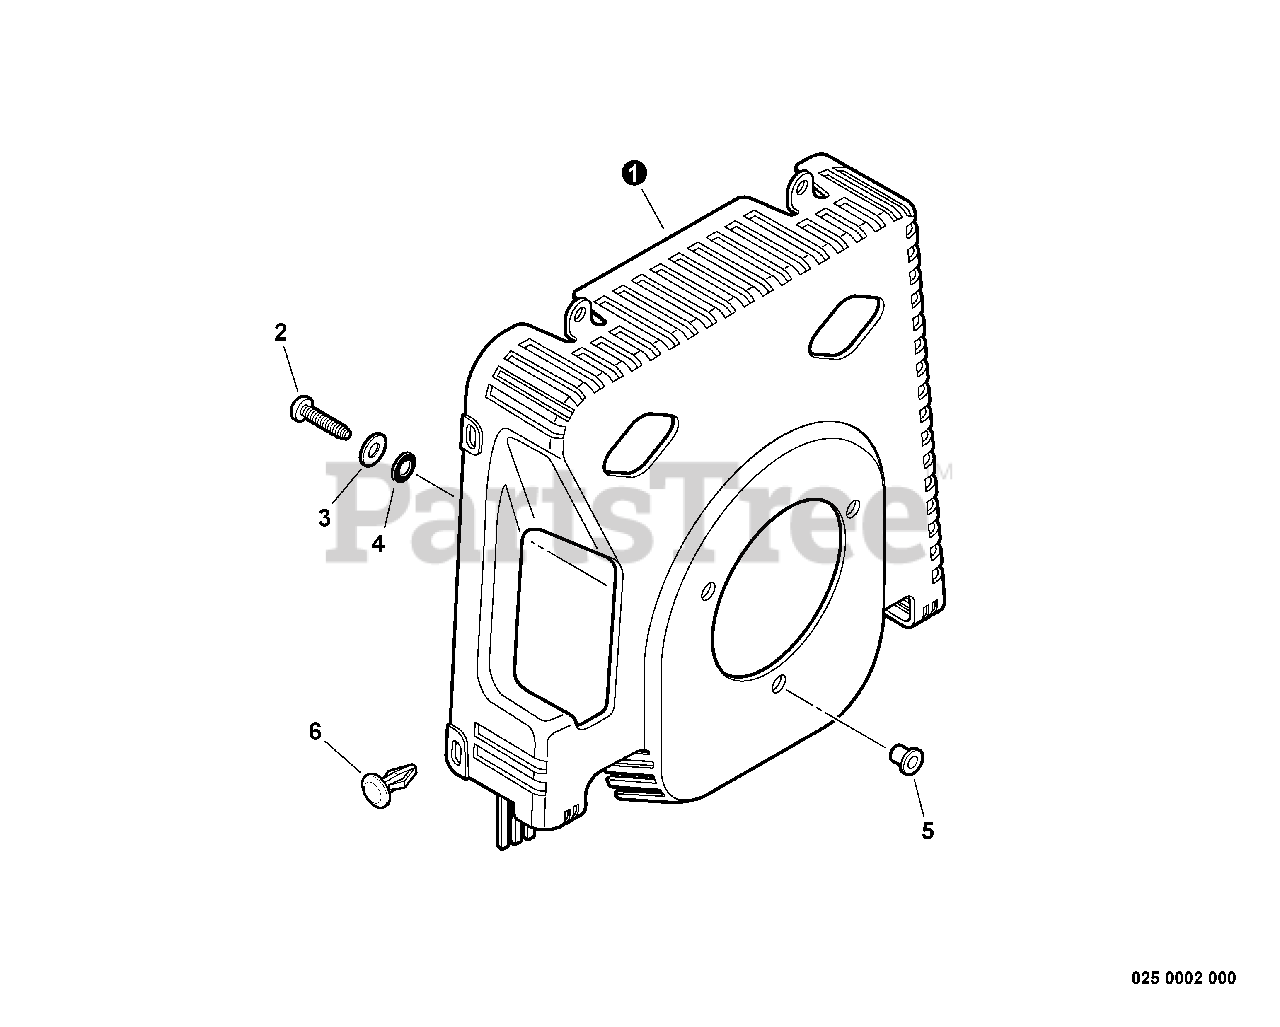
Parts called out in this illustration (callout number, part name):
1	GUARD, DEBRIS
2	SCREW - 5X20 -- TAPPING
3	WASHER - 5
4	WASHER - RUBBER
